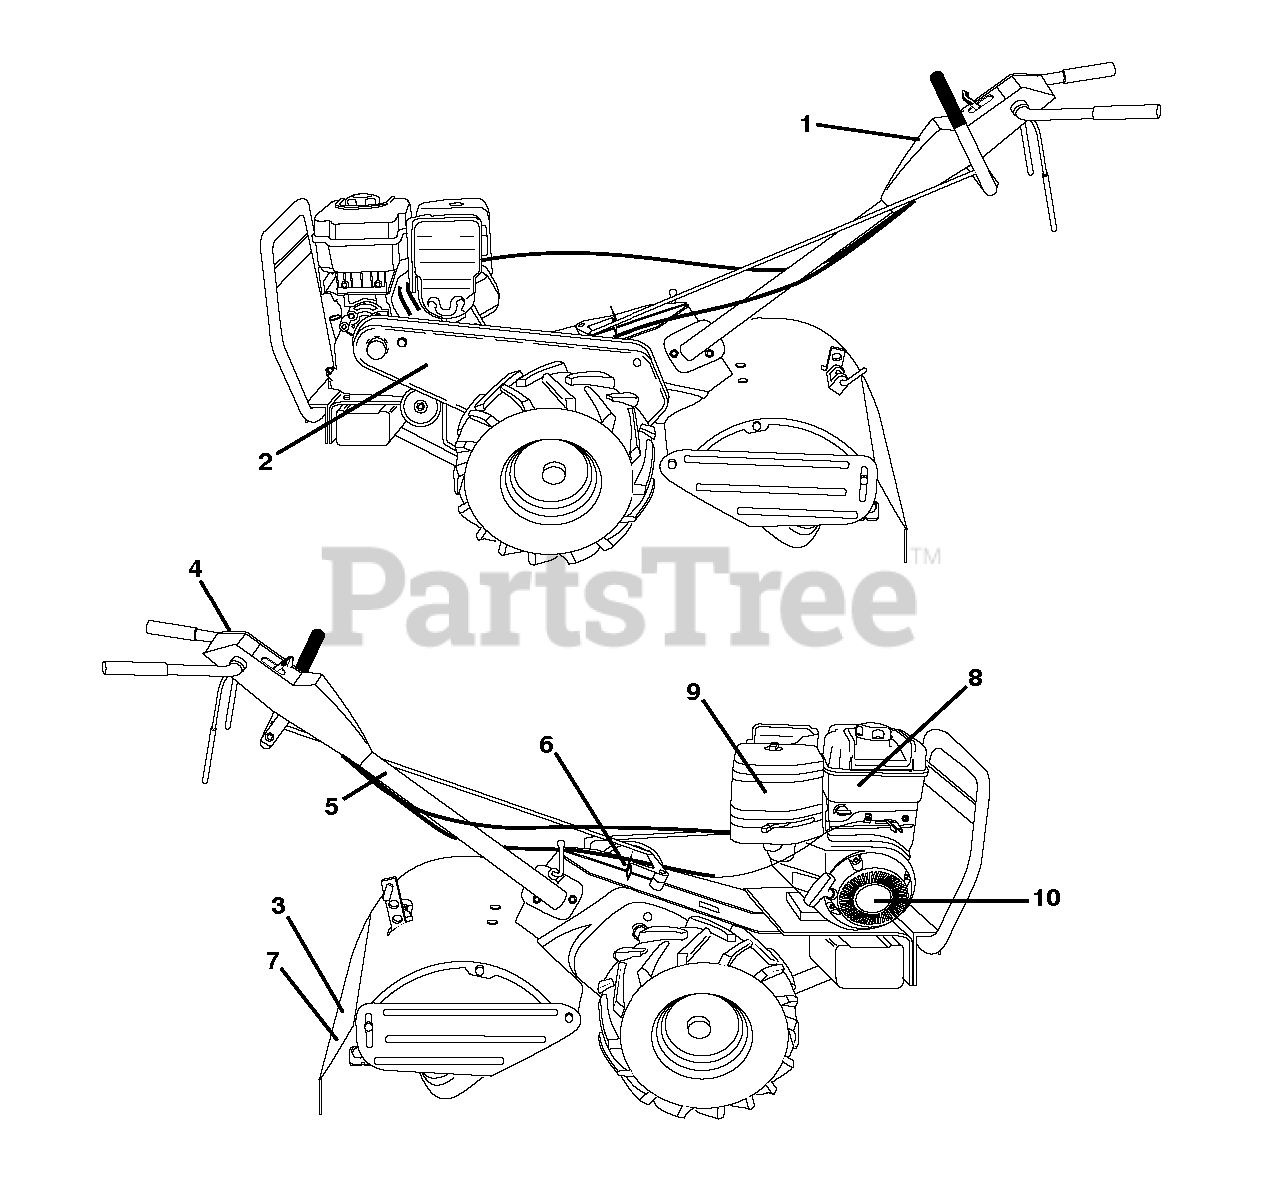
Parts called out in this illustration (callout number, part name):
2	DECAL.HOOD.LOGO.ORANGE.HUSQVAR
3	DECAL EUROPE STANDARD CE
5	DECAL.PLACEMENT.HAND.SYMBOLS
6	DECAL, SHIFT INDICATOR
7	DECAL.WARNING.4-SYM.TILLER.INT
10	DECAL, REWIND STARTER, B&S
